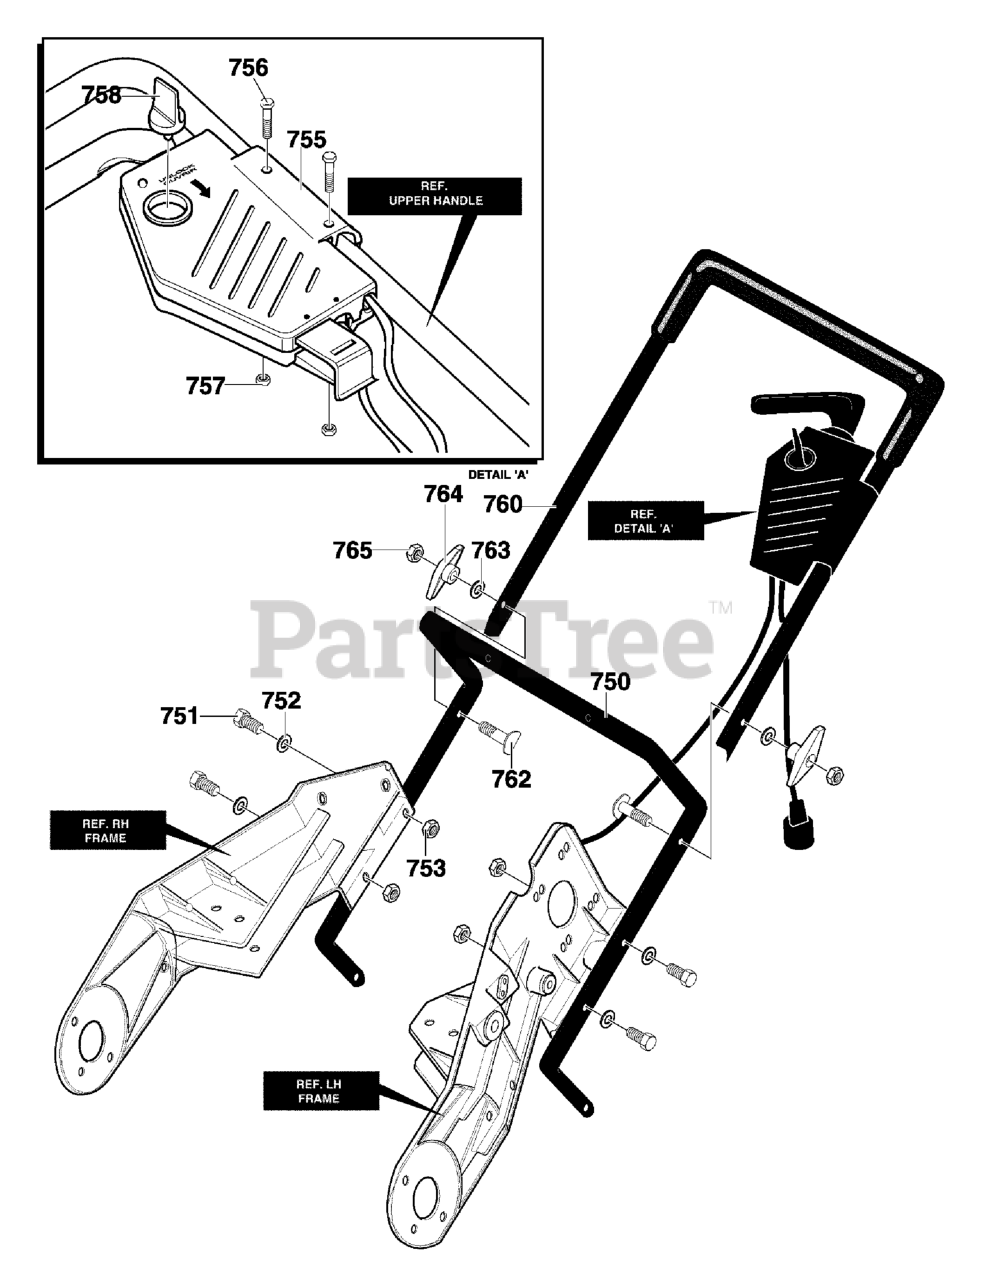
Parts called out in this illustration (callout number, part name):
750	HANDLE, LOWER
751	SCREW, 1/4-20 x 1.25
752	FLATWASHER
753	NUT, 1/4-20
755	ASSY, SWITCH BOX
756	SCREW, 10-24
757	NUT, #10-24
758	KEY, SWITCH BOX
760	UPPER HANDLE ASSY.
762	BOLT, 5/16-18 x 2.00
763	WASHER, FORMED
764	T KNOB
765	NUT, 5/16-18
